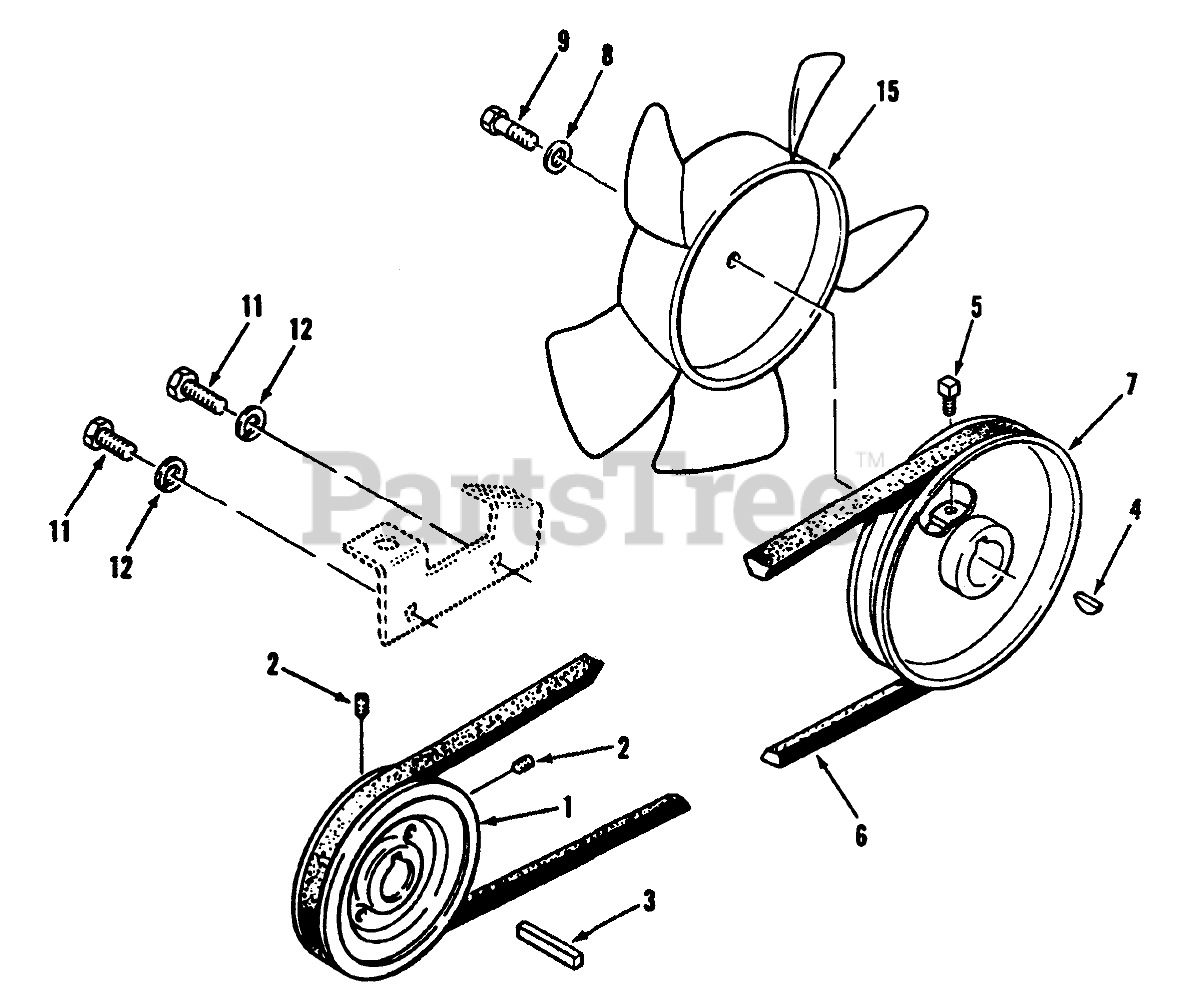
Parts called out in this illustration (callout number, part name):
1	PULLEY
2	SCREW-SET, HSH
4	KEY-WOODRUFF
5	SCREW-SQH
6	BELT-V
7	PULLEY
8	WASHER
9	SCREW-HH
11	SCREW-HH, LOCK
12	WASHER-PLAIN
15	NYLON FAN-L-CW
